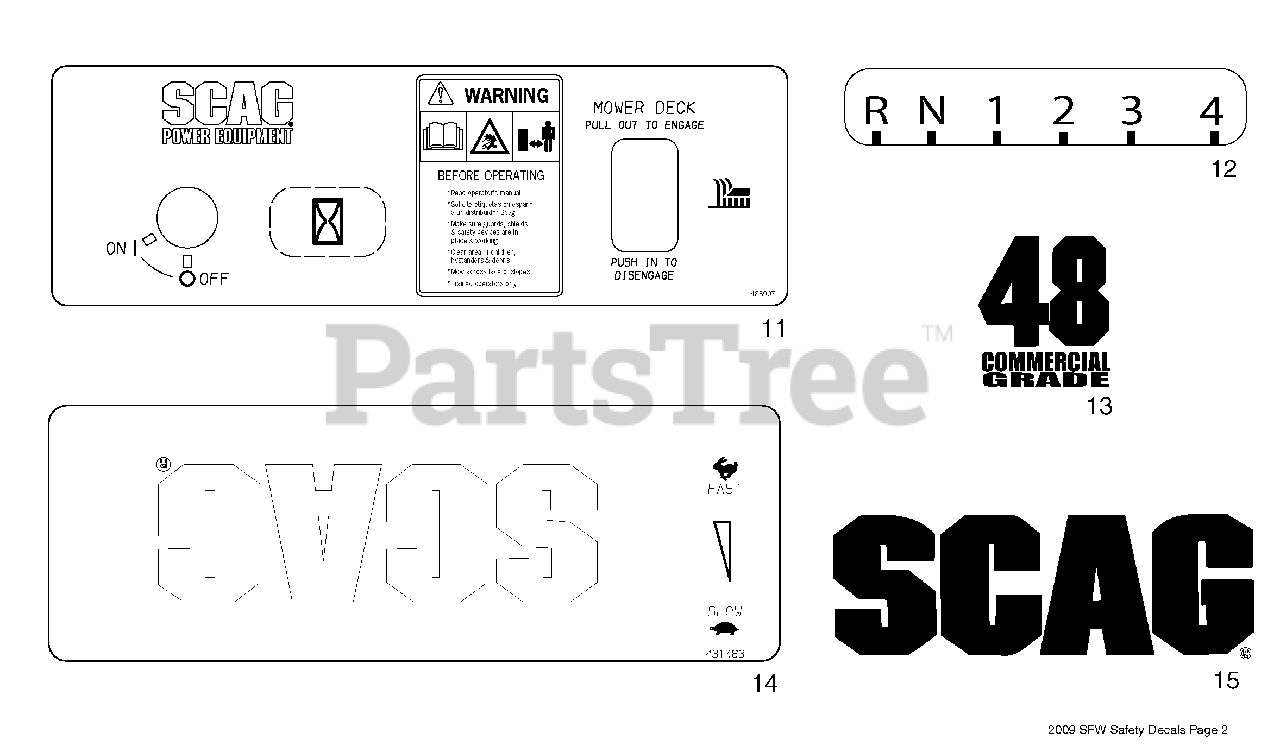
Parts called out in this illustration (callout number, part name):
11	Decal, Instrument Panel Rear
12	Decal, Shift Index SFW
13	Decal, 48 Commercial
14	Decal, Instrument Panel Front
15	Decal, Scag Logo
